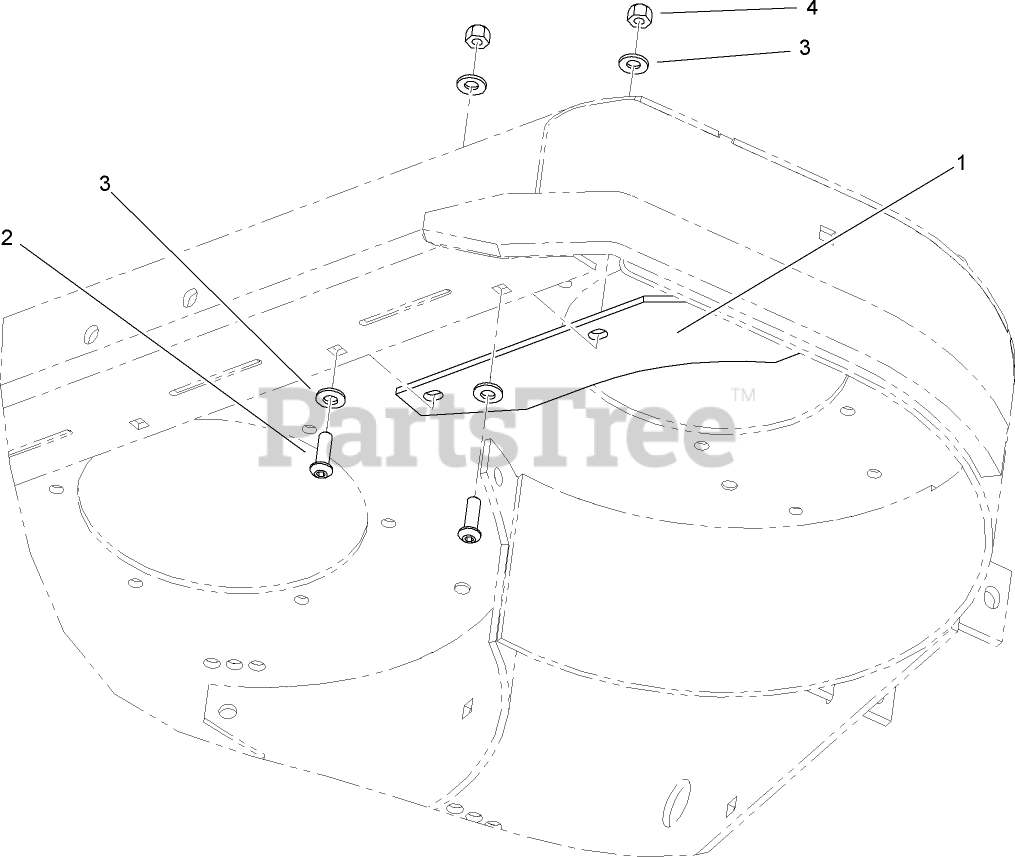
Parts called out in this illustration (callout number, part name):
1	PLATE-TURBO
2	SCREW-HSBH
3	WASHER-SPRING
4	NUT-LOCK, NI
